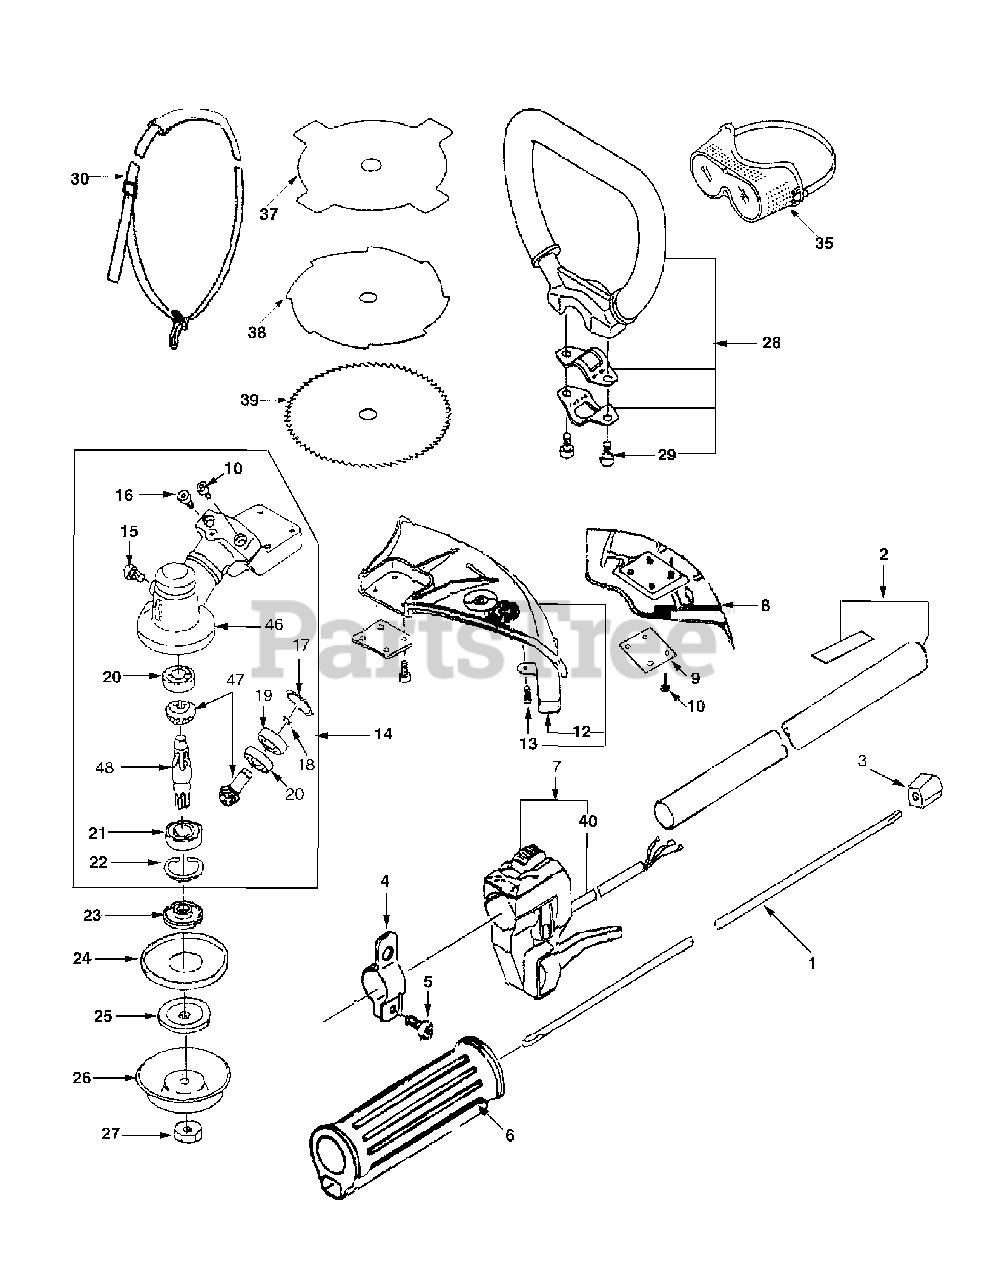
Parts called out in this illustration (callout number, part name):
1	Shaft, Drive
2	Pipe Complete
5	Bolt; M6 X 14
7	Lever Assy,Throttle
8	Deflector
10	Bolt; M5 X 20
13	Bolt; M5 X 16
14	Case Ass'y, Gear
15	Bolt; M6 X 8
16	Bolt; M5 X 10
17	Snap Ring; R-26
18	Snap Ring; S-10
19	Bearing Ball; 6000ZZ
20	Bearing Ball; 6000
21	Bearing Ball; 6001LL
22	Snap Ring; R-28
24	Cover(B)
26	Cover, Bolt
27	Nut; Left M10 1.25
29	Bolt; M6 X 12
30	Band Complete, Shoulder
31	Wrench; 19
32	Wrench Key; 4mm
33	Bag, Tool
34	Book, Instruction
35	Goggle
37	Blade (4 Tooth)
38	Blade (8 Tooth)
39	Blade (Circular)
40	Wire Compl, Throttle
46	Case, Gear
47	Gear Ass'y
